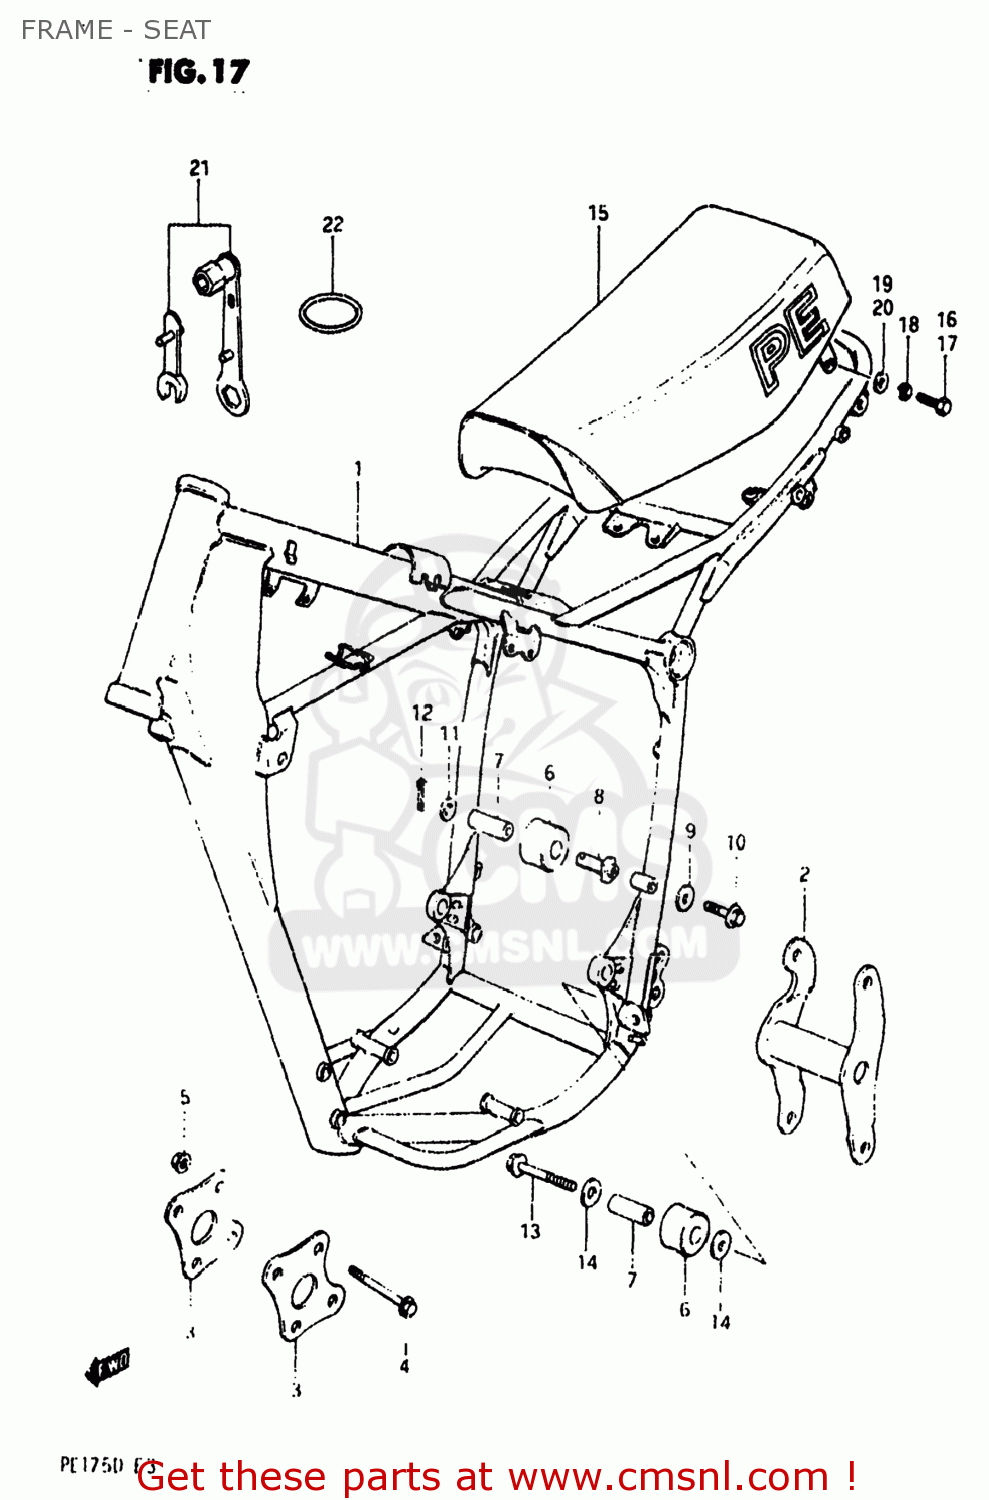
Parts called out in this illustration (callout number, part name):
1	FRAME
2	PLATE,ENGINE MOUNTING
3	PLATE,ENGINE MOUNTING
4	BOLT(8X67)
5	NUT
6	ROLLER,CHAIN LENGTH CONTROL
7	SPACER,CHAIN LENGTH ROLLER
8	BOSS,CHAIN LENGTH ROLL
9	WASHER
10	BOLT
11	WASHER
12	PIN 25X20
13	BOLT(8X45)
14	WASHER
15	SEAT ASSEMBLY
16	BOLT
17	BOLT 8X45
18	LOCK WASHER
19	WASHER (8.5X20X2.6)
20	WASHER (8.7X22X2)
21	SPARK PLUG WRENCH
22	O RING TOOL FITTING
